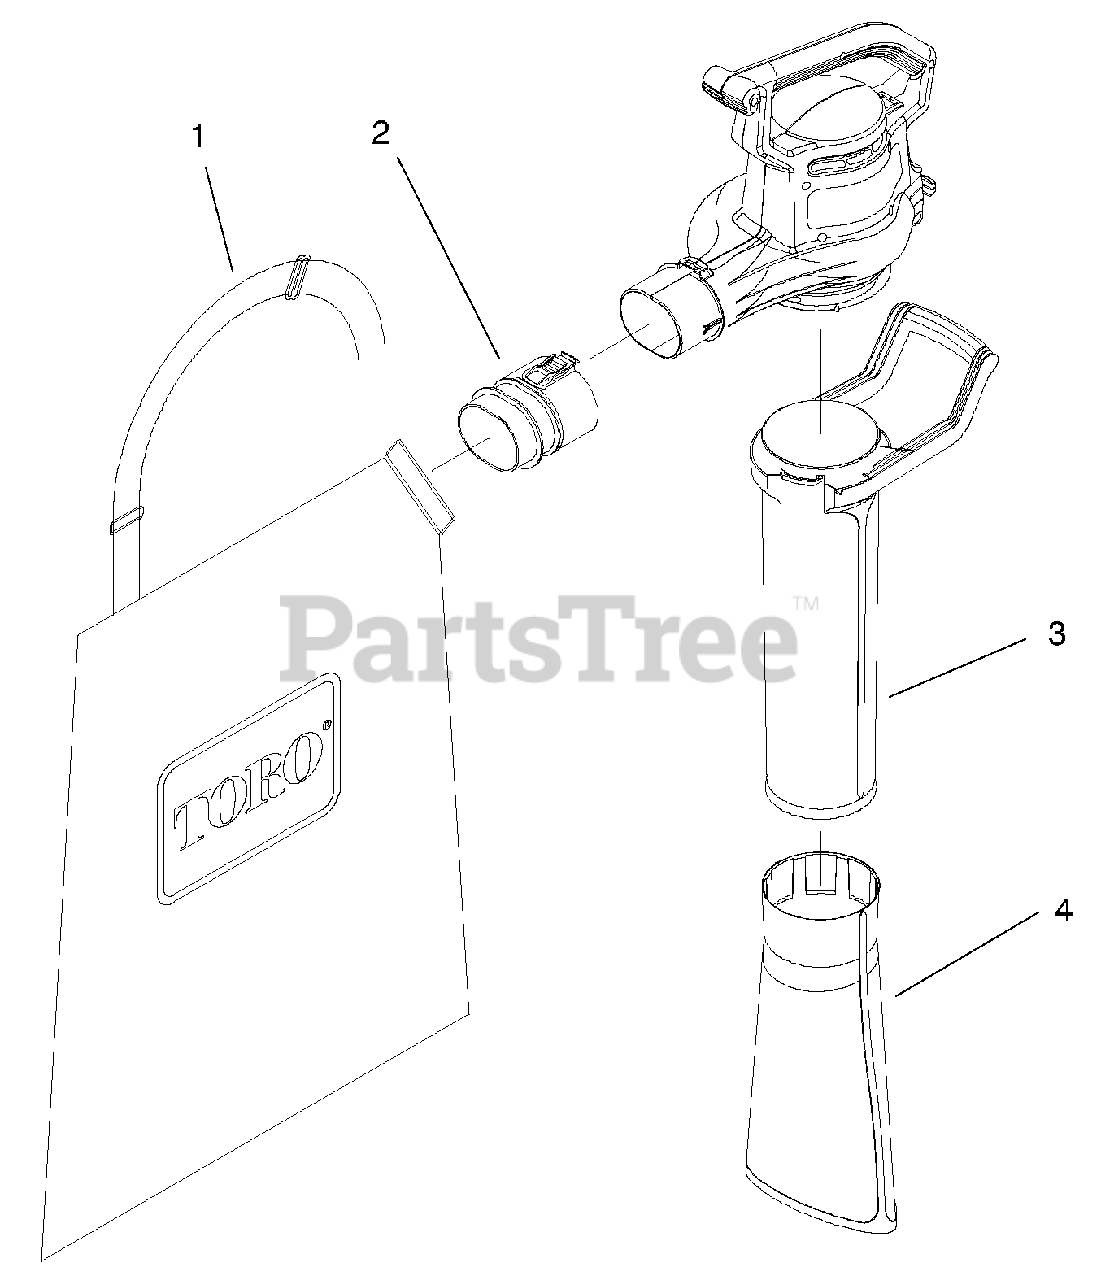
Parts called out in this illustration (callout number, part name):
1	Bag
2	Tube-Bag Inlet
3	Tube-Vac Upper
4	Tube-Vac Lower
